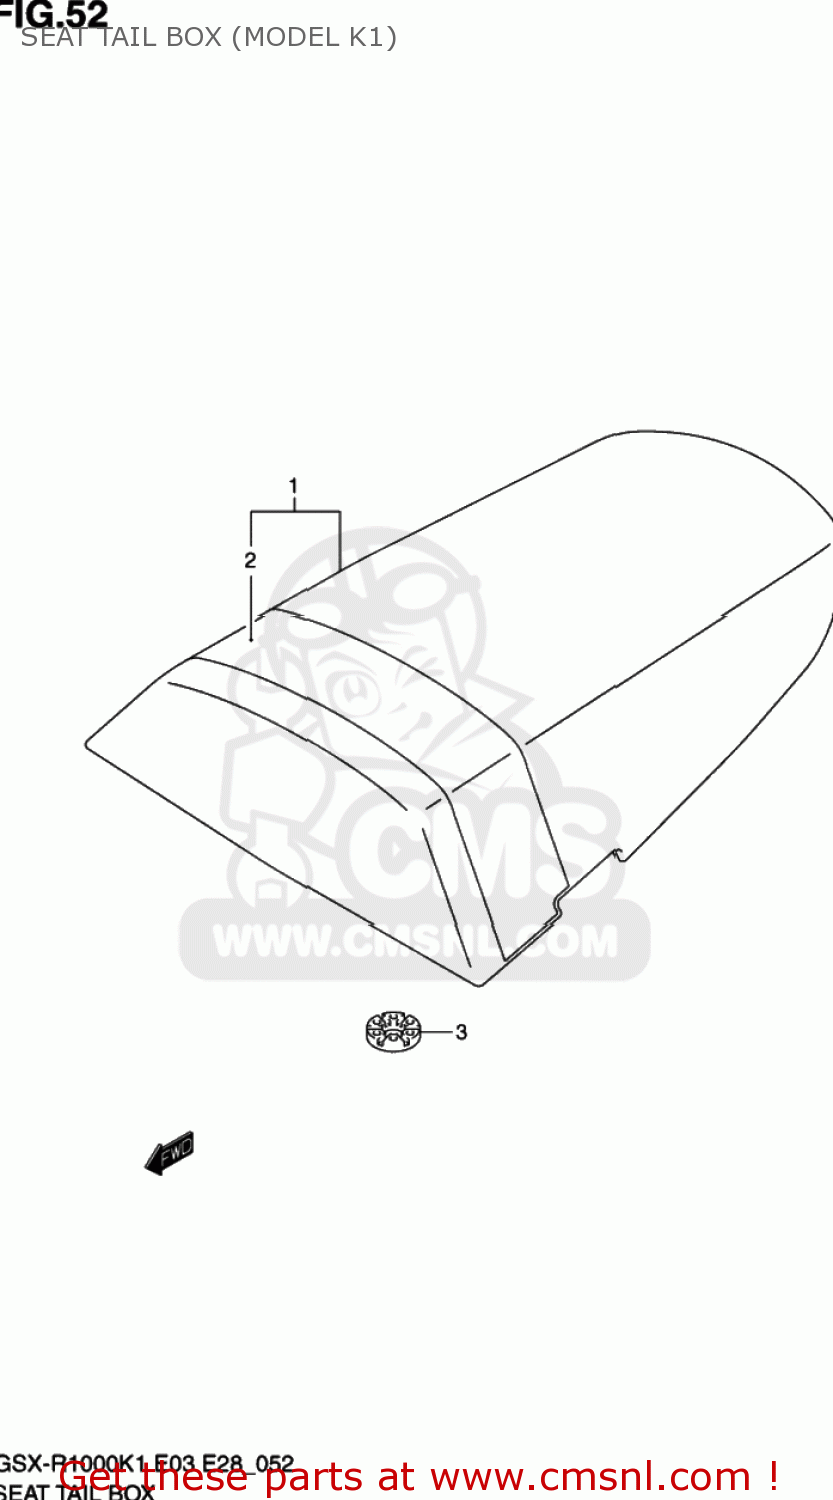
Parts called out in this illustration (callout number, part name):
1	BOX ASSY,SEAT TAIL(BLACK)
2	TAPE,BOX SEAT TAIL
3	CUSHION
